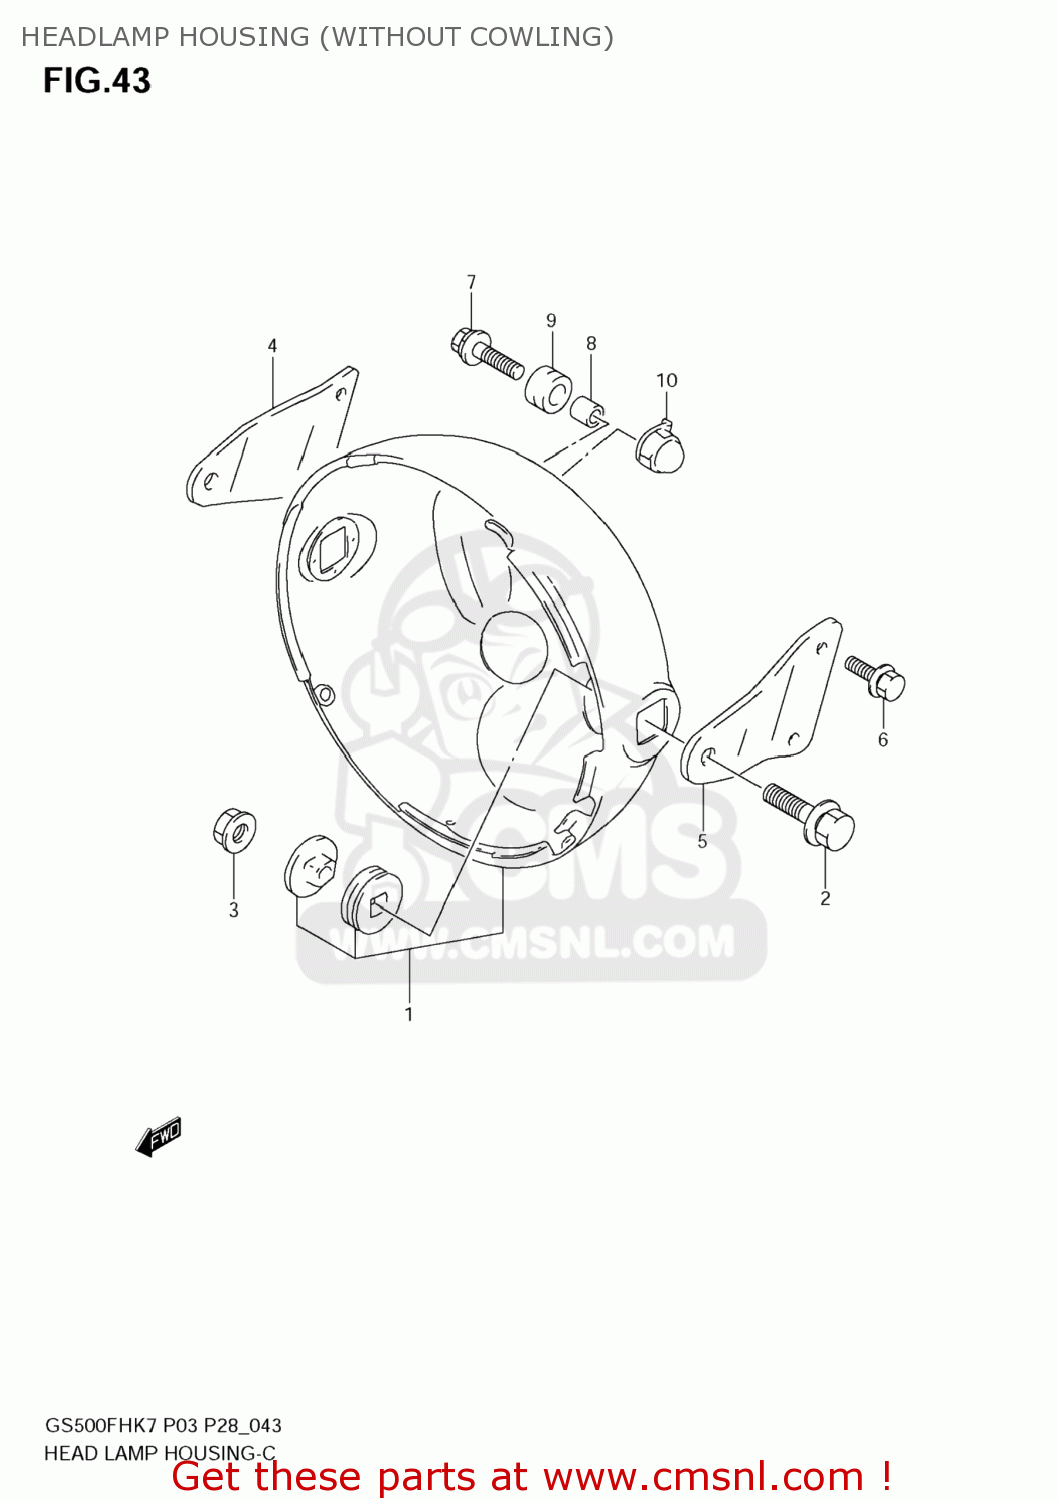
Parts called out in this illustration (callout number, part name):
1	HOUSING,HEADLAMP
2	BOLT
3	NUT
4	STAY,HEADLAMP
5	STAY,HEADLAMP
6	BOLT
7	BOLT
8	SPACER(6.5X10.5X12)
9	CUSHION
10	PLATE,HEADLAMP
